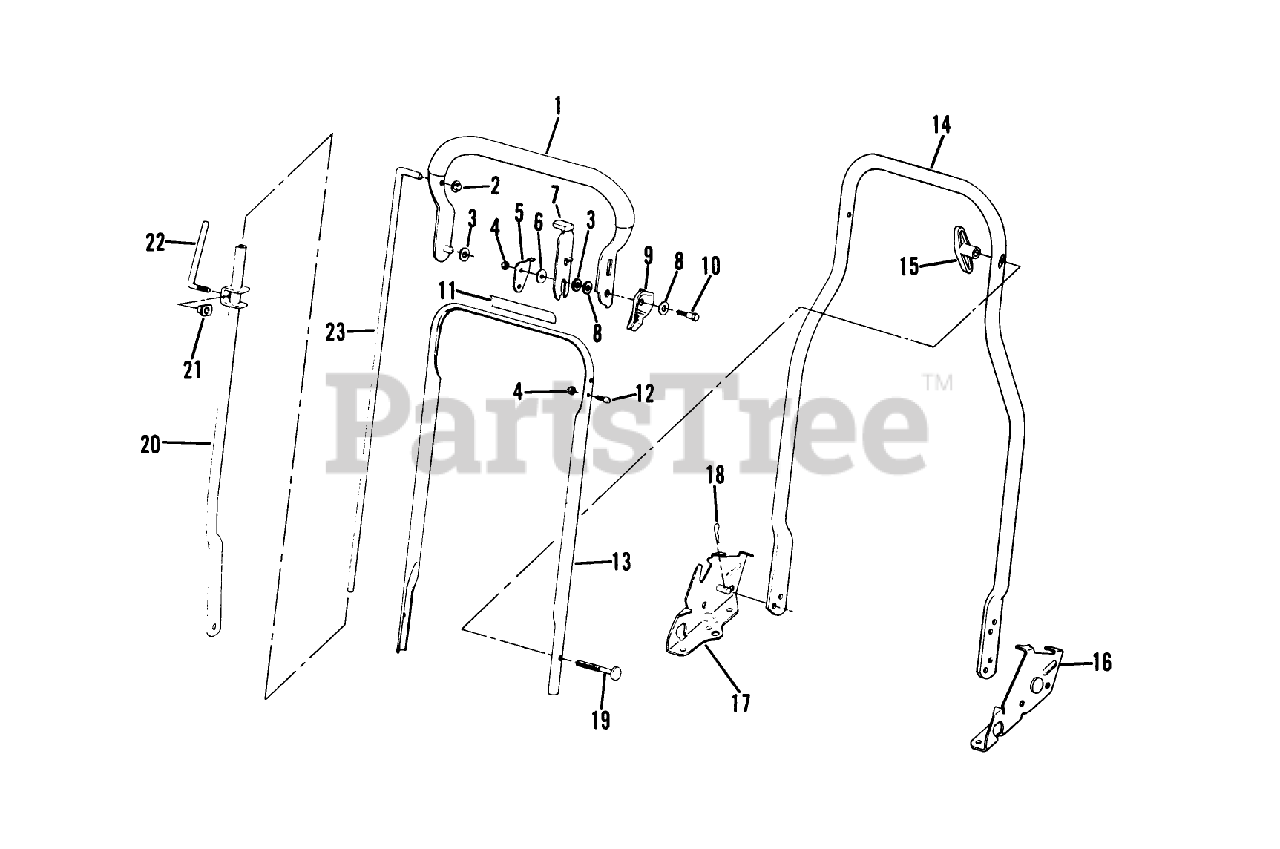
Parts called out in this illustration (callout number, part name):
3	WASHER M
4	LOCKNUT E
5	HANDLE STOP
6	WASHER
7	LEVER LOCKOUT
10	BOLT PIONEER
12	SCREW-HANDLE STOP
13	HANDLE
15	NUT-WING
17	HANDLE BRACKET
18	HAIR PIN
23	ROD CONTROL
